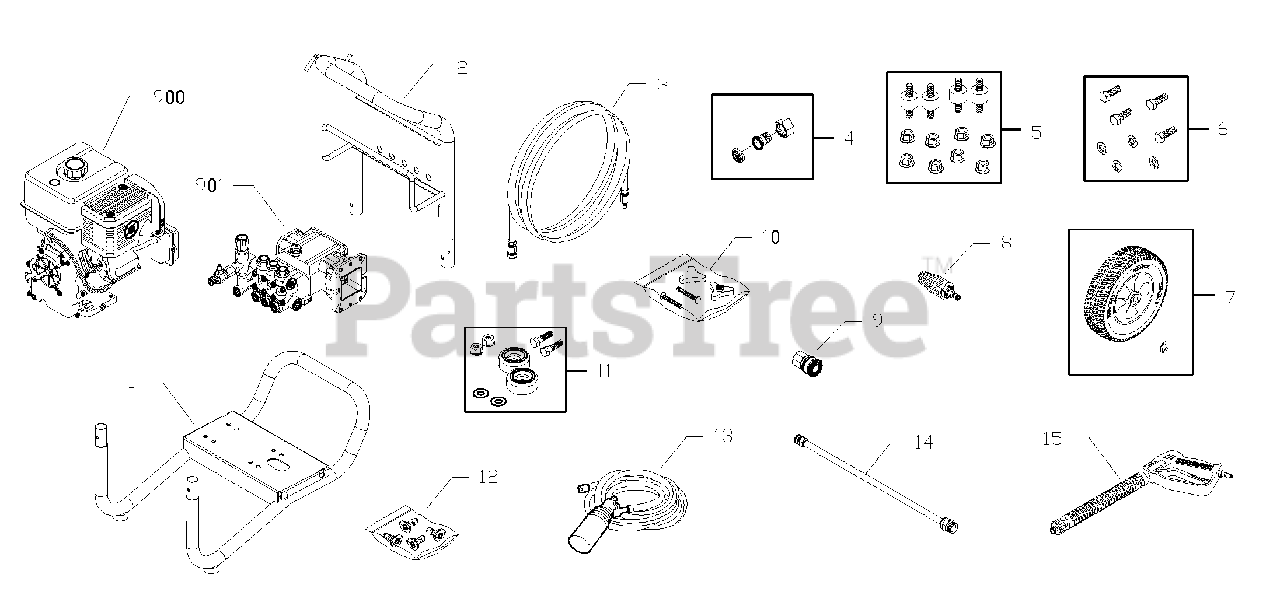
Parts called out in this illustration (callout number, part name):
4	KIT, Connector, Hose, Garden
5	KIT, Engine Hardware
6	KIT, Pump Hardware
9	FITTING, Quick Connect
10	KIT, Handle Fastening
11	KIT, Vibration Mount
12	KIT, Nozzle, QC
13	DISPENSER, Soap
14	ASSY, Wand, QC
15	GUN
900	** ENGINE
901	* PUMP, 66DX40G1I
